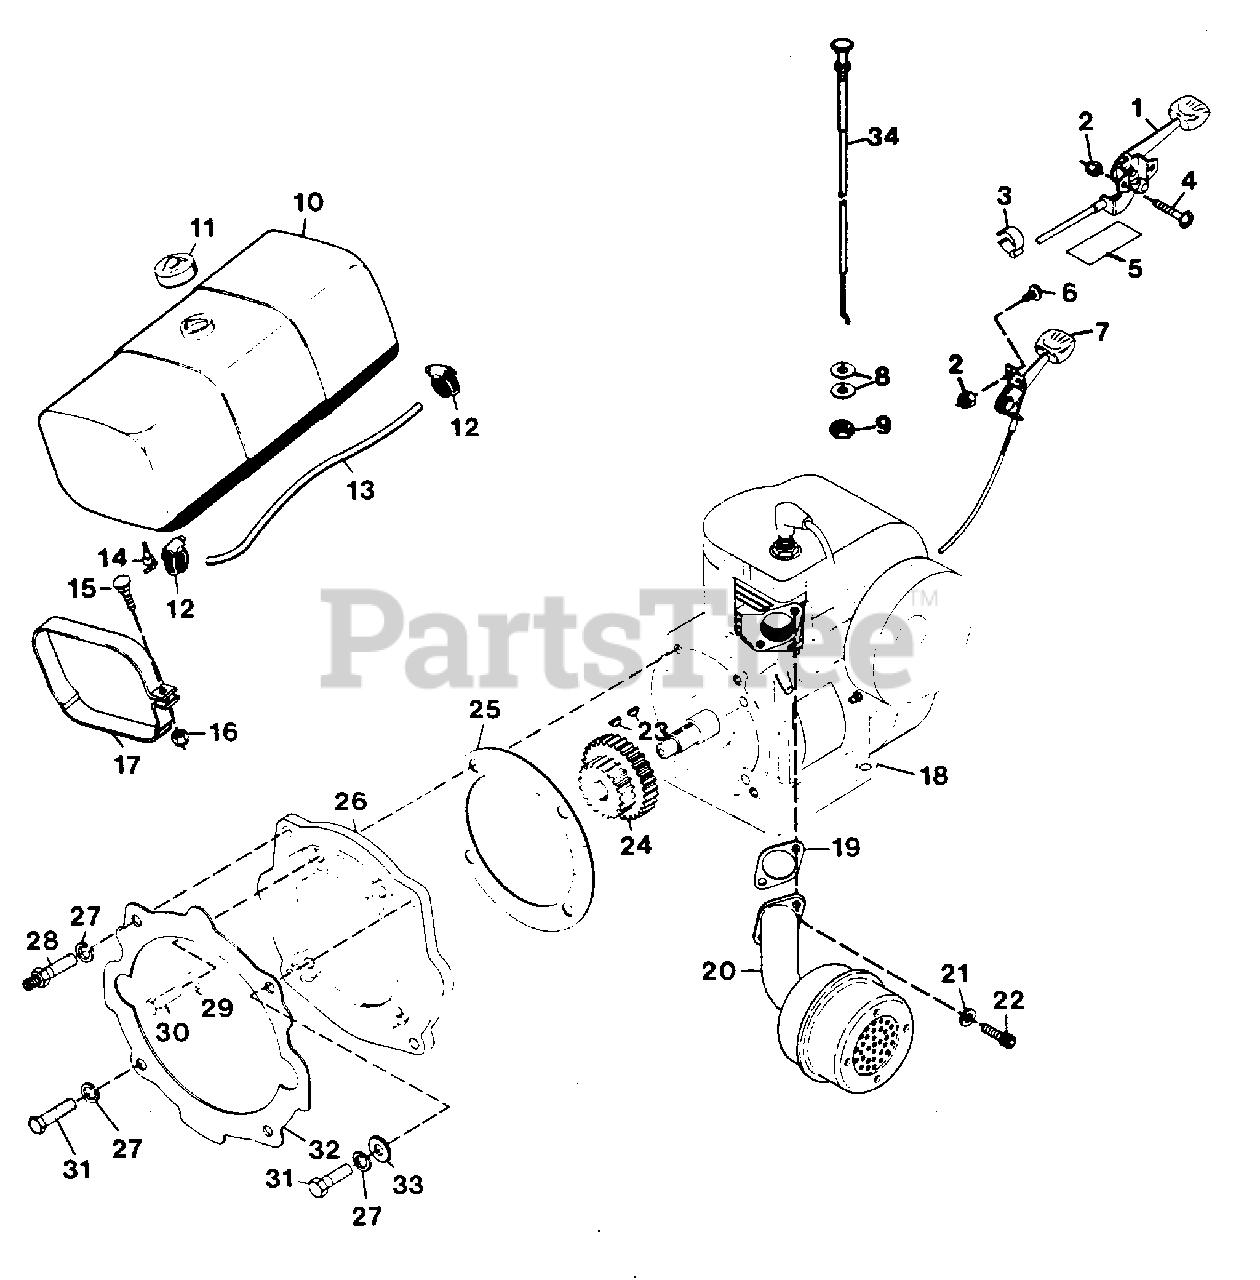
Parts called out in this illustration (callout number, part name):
1	LEVER, THROTTLE CONTROL
2	NUT, LOCK 10-24
3	CLIP, CONDUIT
4	SCREW, MACH. 10-24X1.50 PHD
5	DECAL, THROTTLE
6	SCREW, MACH. 10-24X.50 PHD
7	LEVER, THROTTLE CONTROL
8	WASHER, FLAT .406X.812X.065
9	NUT, HEX JAM 3/8-24
10	ASSEMBLY, FUEL TANK
11	CAP, GAS TANK
12	CLAMP, HOSE
13	LINE, FUEL
14	VALVE AND STRAINER
15	BOLT, 1/4-20X1.75 RD.HD.SQ.NECK
16	NUT, LOCK 1/4-20
17	STRAP, FUEL TANK
18	ENGINE, 12 HP ELECTRIC
18	ENGINE, 12 HP MANUAL
18	ENGINE, 10 HP ELECTRIC
18	ENGINE, 8 HP ELECTRIC
18	ENGINE, 8 HP MANUAL
19	GASKET, EXHAUST
20	MUFFLER
21	WASHER, LOCK 5/16 REG.
22	SCREW, CAP 5/16-18X.75 SHD
23	KEY, WOODRUFF 5/32X5/8 HARD #6
24	GEAR, 10/12 DP 21/30 TEETH
25	GASKET, ENGINE TO ADAPTOR
26	ADAPTOR, ENGINE
27	WASHER, LOCK 7/16 SP HEAVY
28	STUD
29	WASHER, LOCK 3/8 SP HEAVY
30	BOLT, HEX 3/8-16X1.00
31	BOLT, HEX 7/16-14X1.25
32	GASKET, CHASSIS TO ADAPTOR
33	WASHER, FLAT .469X.938X.065
34	LEVER, CHOKE CONTROL
